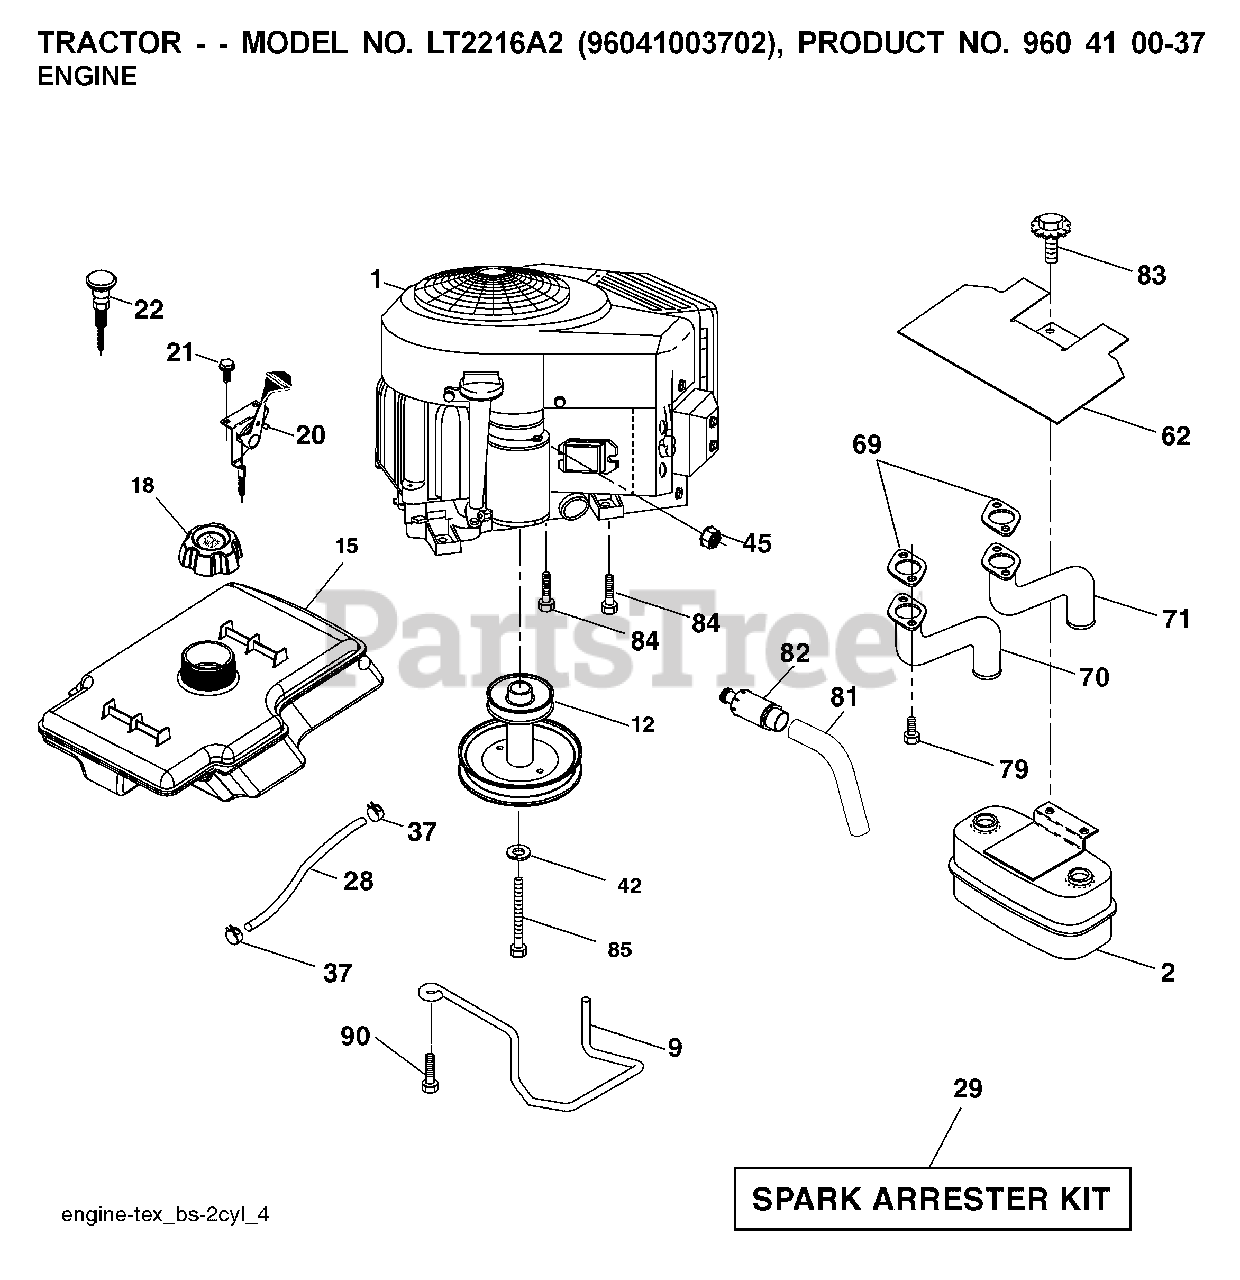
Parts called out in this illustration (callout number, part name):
2	MUFFLER.TWIN.CYL.LOW.TONE
9	KEEPER.BELT.ENGINE.3.25
12	PULLEY ENGINE
18	CAP.ASM.FUEL.TANK.3"BL
20	THROTTLE CABLE
21	SCREW.#10 X 0.750.BOS THREAD
22	CONTROL CHOKE
29	ARRESTER SPARK (OPTIONAL)
37	HOSE CLAMP
42	LOCKWASHER
45	NUT
62	RP SHIELD HEAT MUFFLER
69	REPL BY 532 27 22-93
70	TUBE MANIFOLD LH
71	EXHAUST TUBE RH
79	SCREW.SOCKET.HEAD.5/16-18
81	TUBE, DRAIN OIL ASM.
82	PLUG DRAIN OIL EASY
83	BOLT, 5/16-18 X 1 3/4
84	SCREW.3/8-16
85	BOLT HEX 7/16-20X4-1/4"
90	SCREW 3/8-16X1
102	SCREW
107	SCREW.1/4-20X5/8
